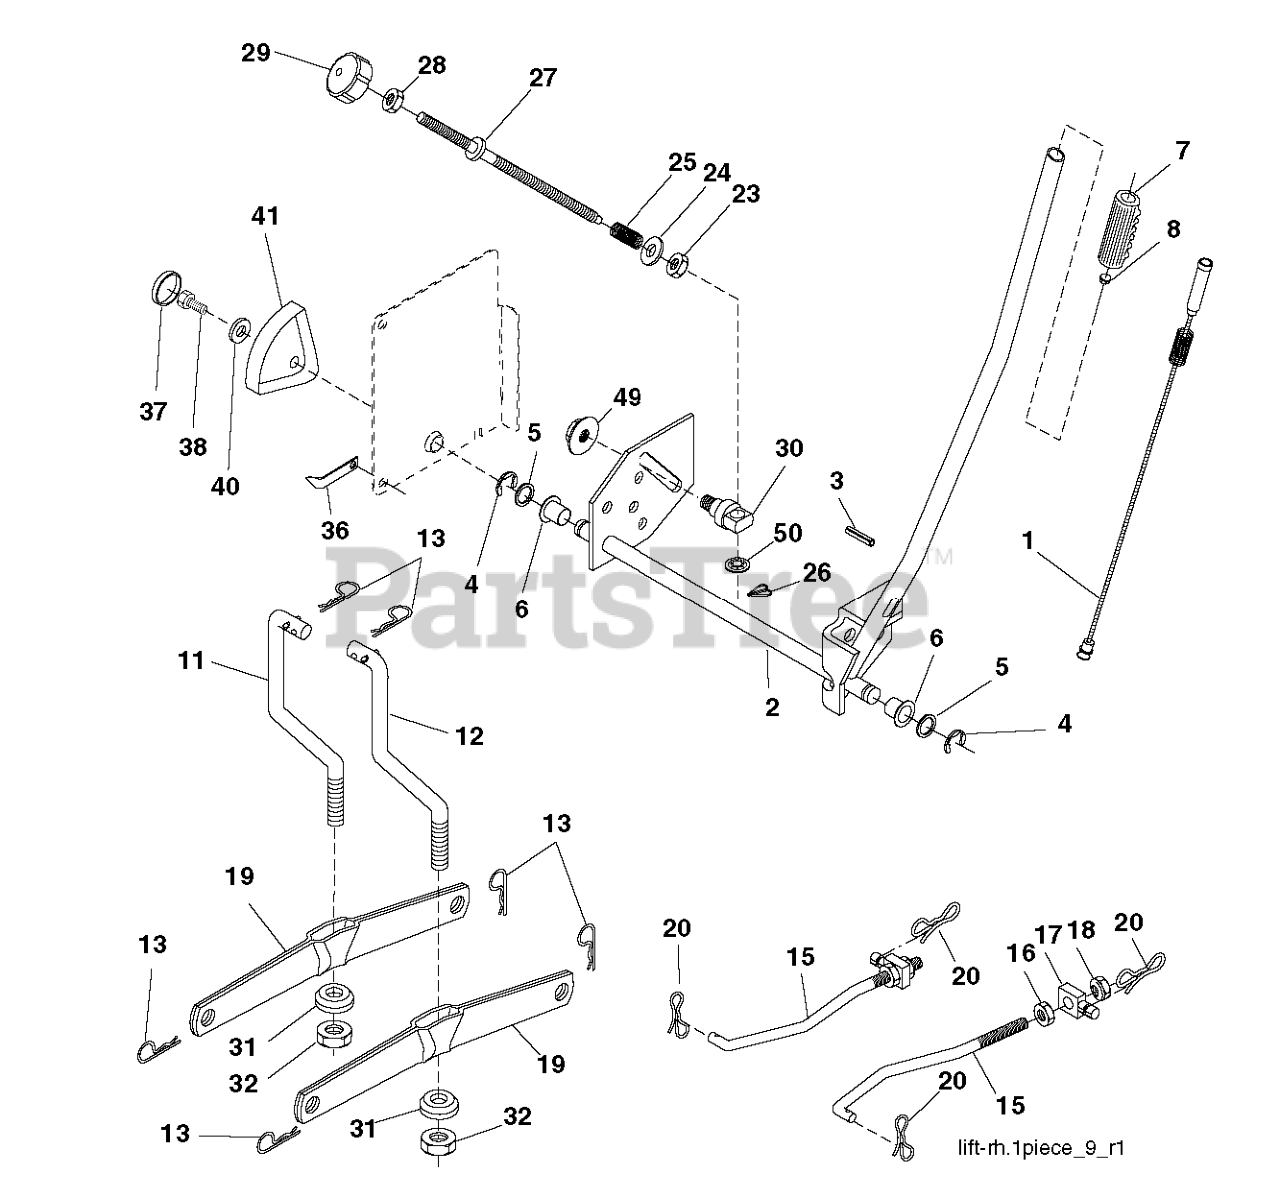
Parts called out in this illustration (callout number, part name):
1	PLUNGER.ASM.LIFT.LVR.BLK.17.32
2	SHAFT ASM R HANDLE
3	PIN GROOVE.
4	RETAINING RING LT
6	BEARING.NYLON
7	GRIP HANDLE
8	PLUNGER BUT KIT
11	LINK
12	LINK
13	RETAINER-SPRNG RB
15	LINK.SUSPENSION.FRONT
16	NUT.HEX.JAM.1/2-13
18	NUT.LK.W/WSH.1/2.
19	ARM.REAR.SUSPENSION
20	PIN.COTTER.7/16.BOW TI.
26	RETAINER CLIP
27	ROD ADJ LIFT
28	NUT
29	KNOB INF 3/8-16
31	BEARING.PIVOT.LIFT
32	NUT CROWNLOCK 3/8-24
36	POINTER, HEIGHT INDICATOR(2 2)
38	SCREW 5/16-18X1
41	HEIGHT INDICATOR
49	NUT
50	NUT PUSH M
